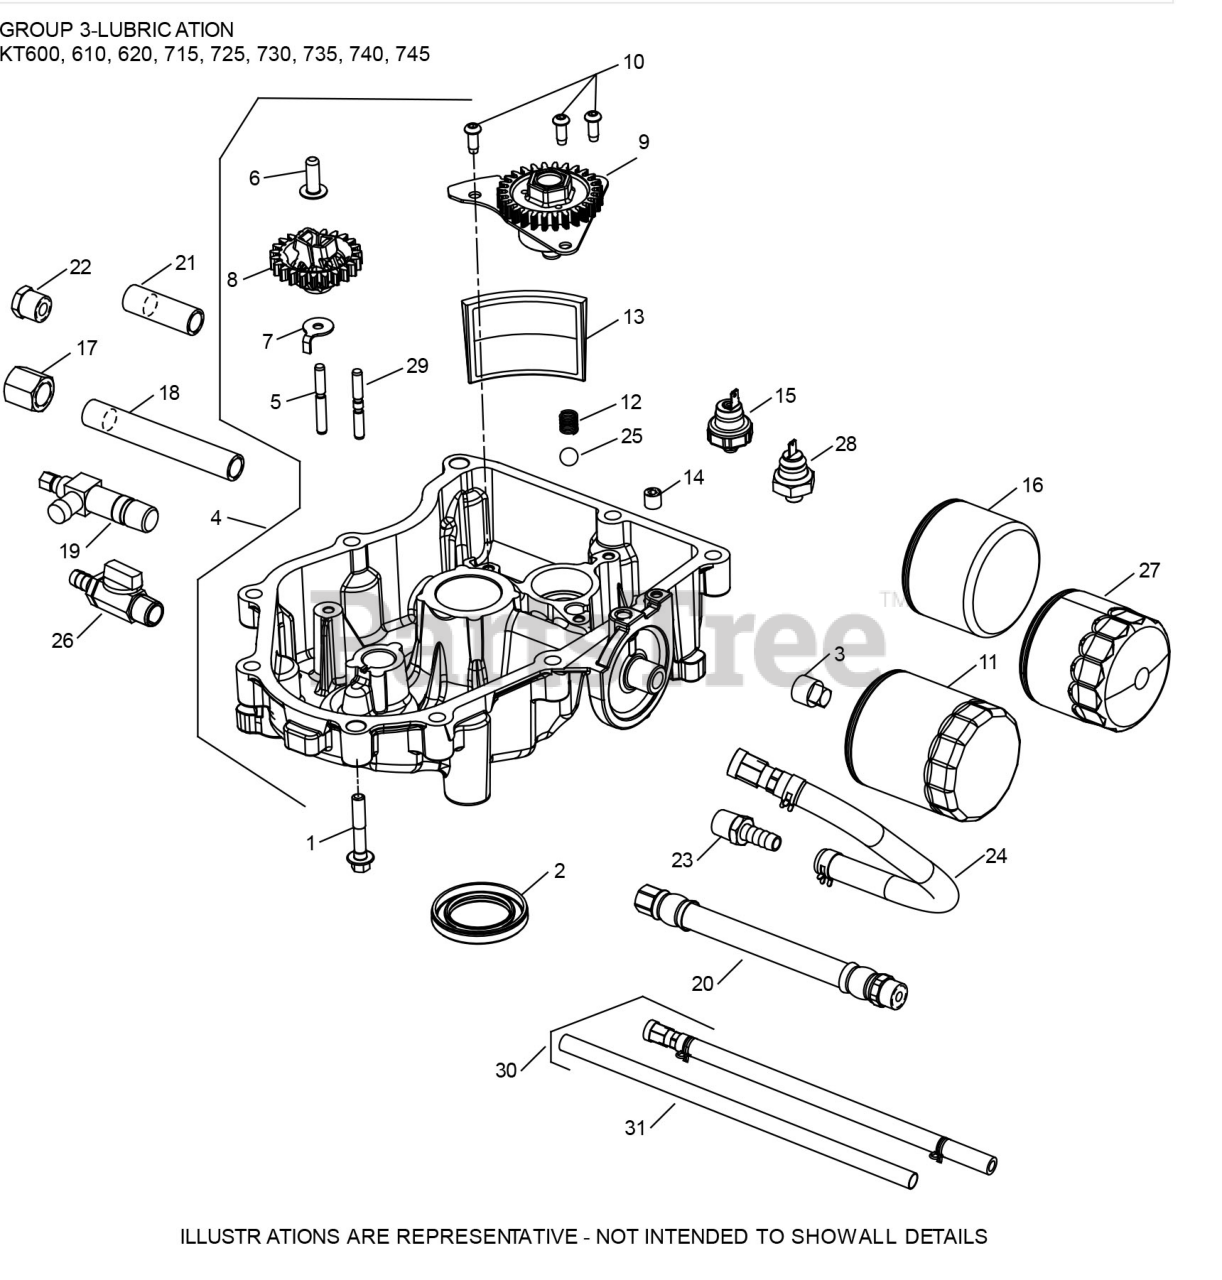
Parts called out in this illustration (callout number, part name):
6	PIN-GOV REGULATING
8	GEAR KIT-GOVERNOR
9	OIL PUMP ASSEMBLY
10	SCREW-BUTTON HEAD
11	OIL FILTER-SHORT (BOXED)
12	COMPRESSION SPRING
25	PRESSURE RELIEF BA
28	OIL PRESSURE SWITCH
29	GOVERNOR GEAR SHAFT
